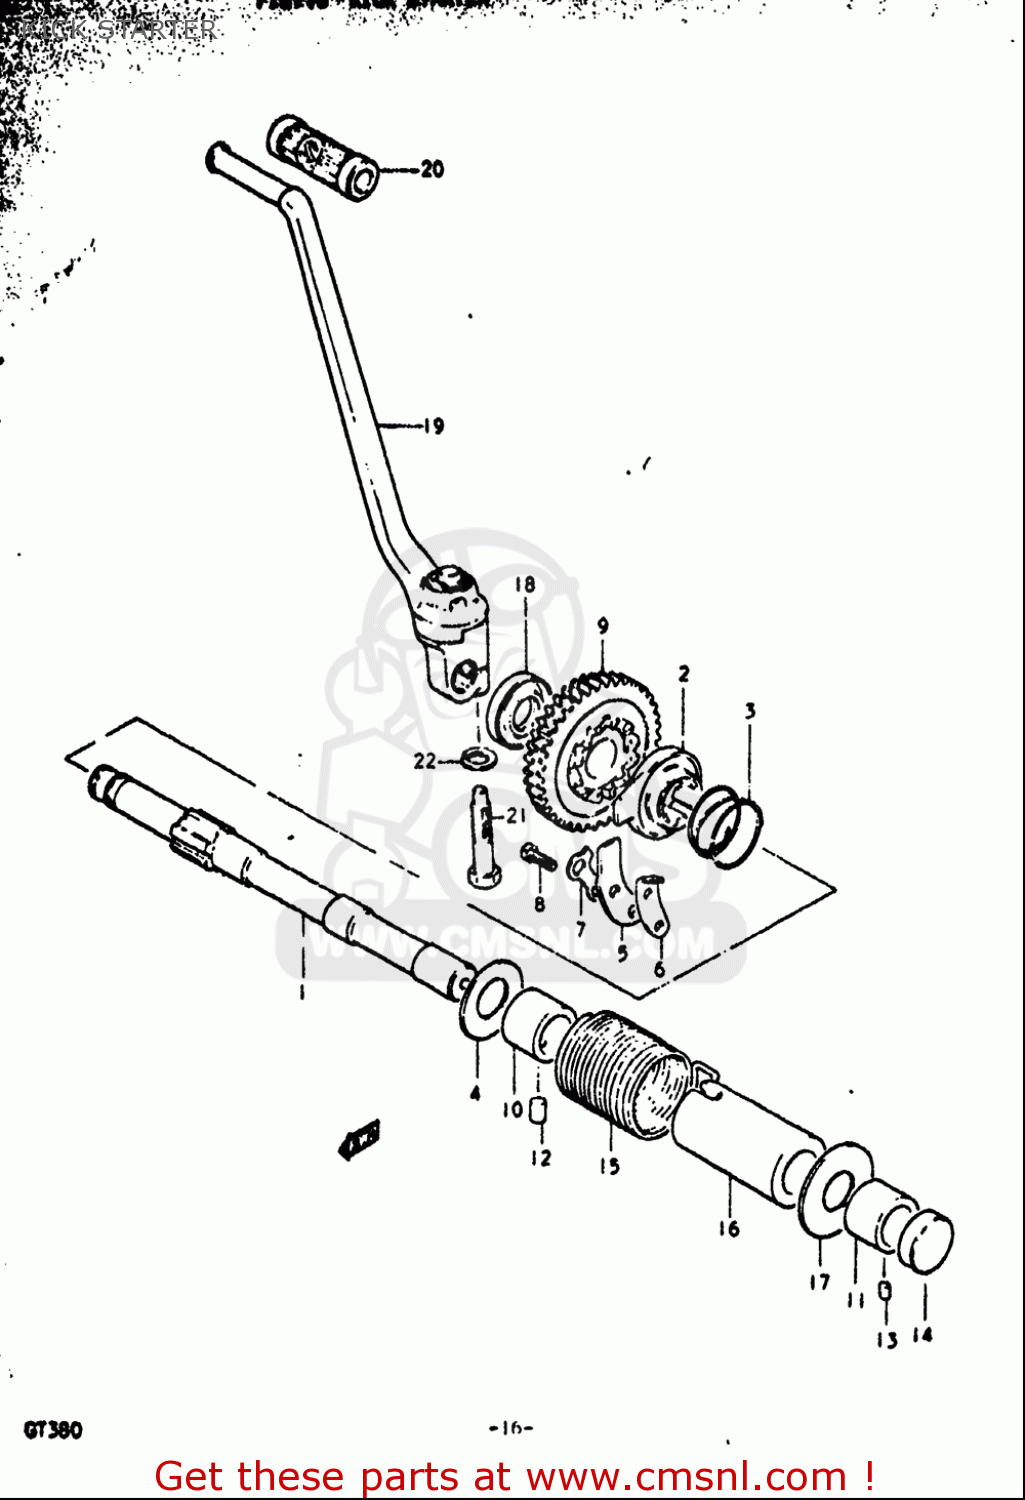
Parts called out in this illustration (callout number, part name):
2	STARTER,KICK
3	SPRING
4	WASHER
5	GUIDE,KICK STARTER
7	WASHER
8	BOLT(6X14)
12	PIN
13	PIN
14	PLUG
15	SPRING
18	SEAL,OIL(16X30X8)
20	RUBBER,KICK STARTER PEDAL
21	BOLT
22	WASHER,LOCK
